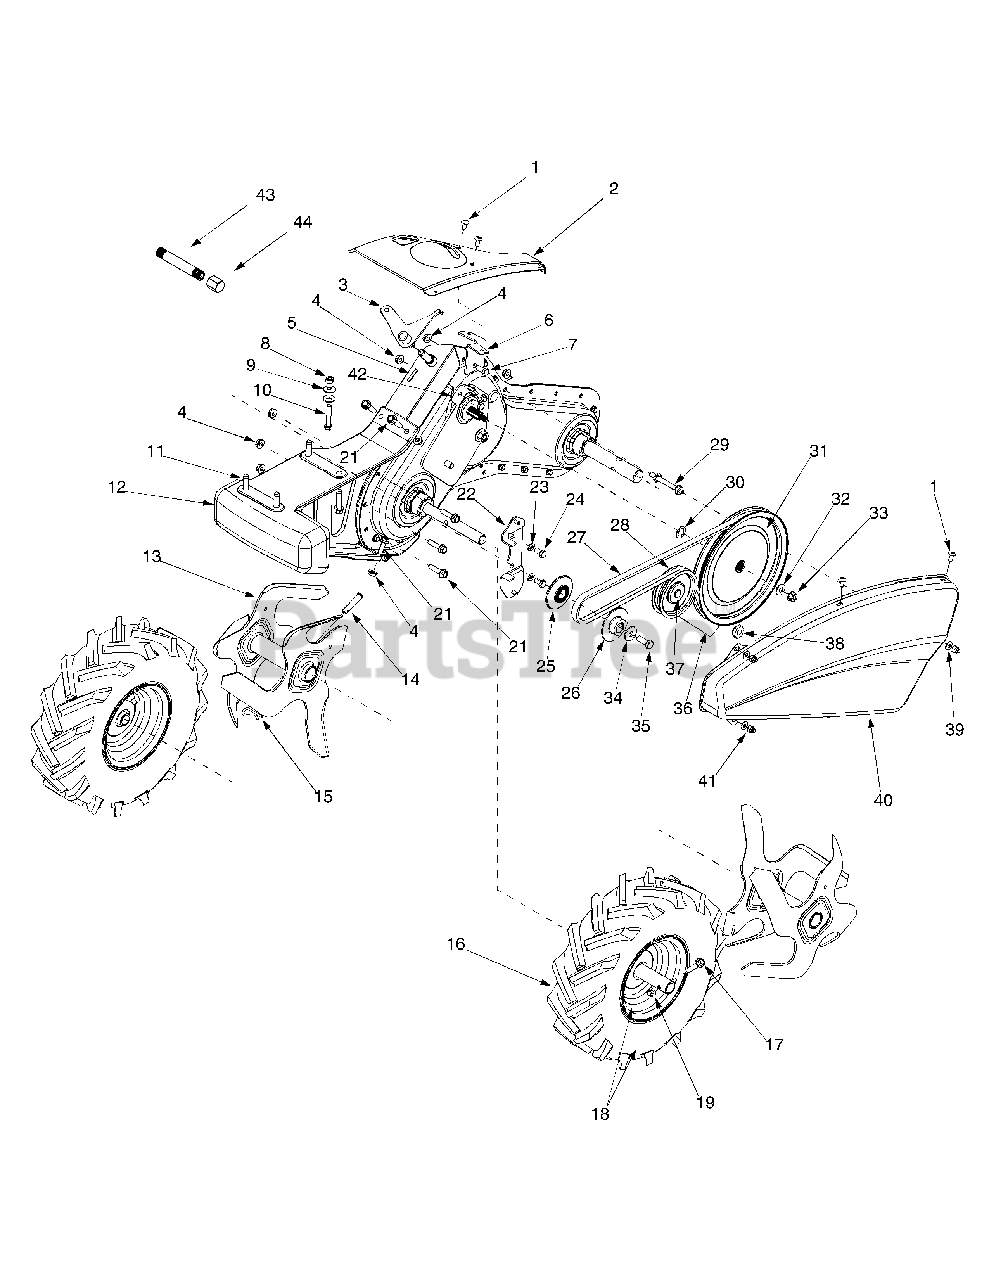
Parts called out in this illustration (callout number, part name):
1	Hex Screw 1/4-20 x.625
5	Spiral Pin
8	Hex Nut 5/16-18
9	Bell Washer.340 ID x.872 OD
10	Hex Cap Screw 5/16-18 x 1.75
11	Hex Washer Screw 3/8-16 x 1.5
12	Frame Counterweight
14	Clevis Pin
15	Cotter Pin
16	Complete Wheel Ass’y - RH (14")
17	Hex Head Screw 1/4-20
18	Rim Only (6.0 x 3.25)
19	Flange Lock Nut 1/4-20
21	Flange Screw 5/16-18 x 1.25
24	Hex Cap Screw 5/16-24 x.625
25	Inner Pulley Half
26	Outer Pulley Half
27	V-Belt
28	Flat Idler
29	Bolt 5/16-18 x 1/4-28 x 2.35
30	Flat Washer.635 ID x.930 OD
31	Flat Pulley
32	Spring Washer.401 ID x.870 OD
33	Flange Lock Nut 3/8-24
34	Bell Washer.396 ID x 1.140 OD
35	Hex Cap Screw 3/8-24 x 1.0
37	Hex Cap Screw 3/8-16 x 1.25
38	Shoulder Nut 7/16-20
39	Flat Washer.271 ID x.630 OD
42	Cable Bracket
43	Oil Drain Extension
44	End Cap
